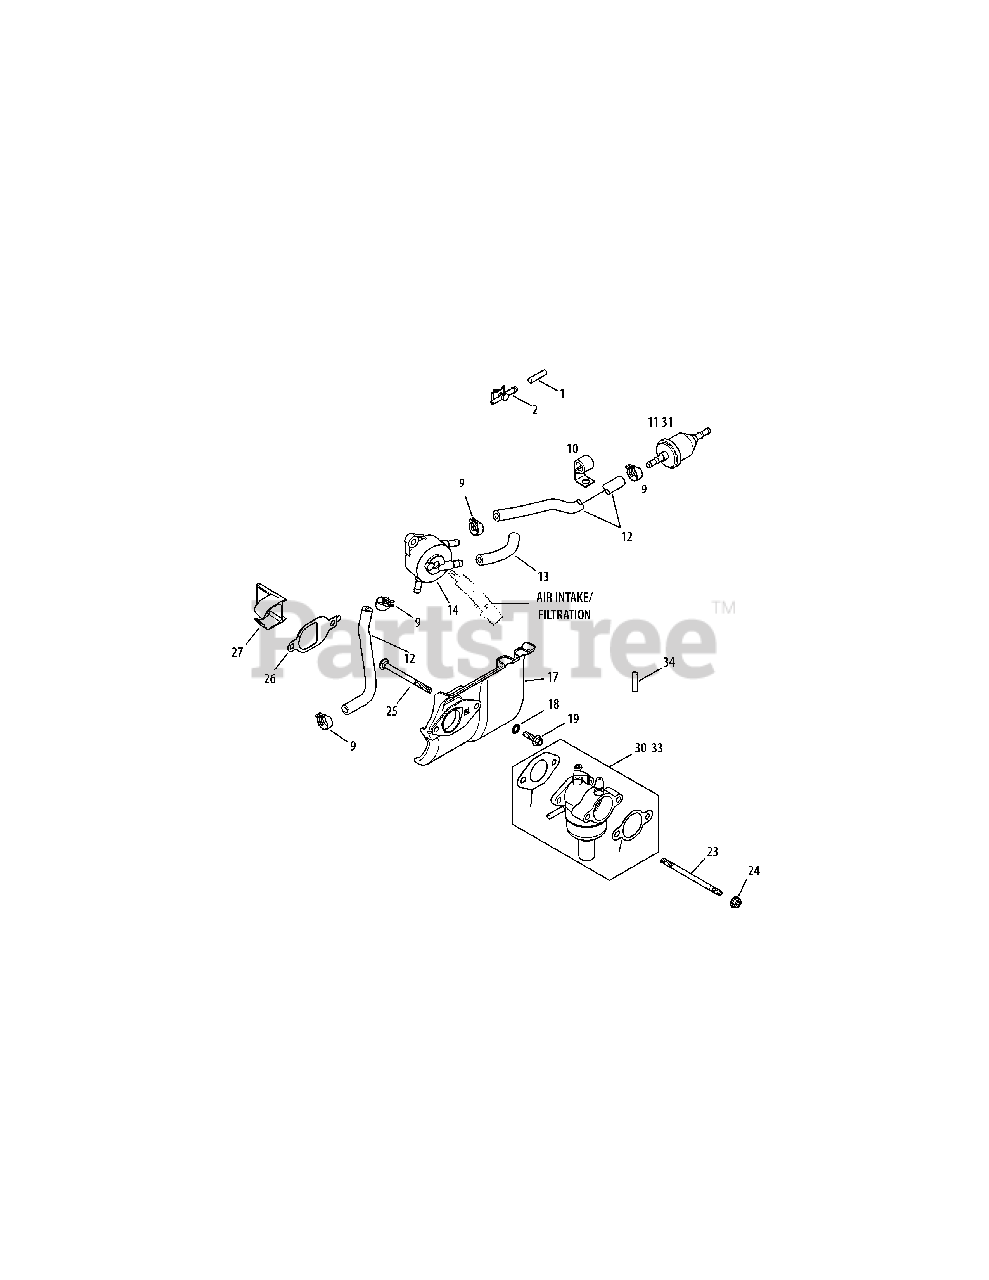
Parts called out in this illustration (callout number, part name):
2	SAI Connector
9	Hose Clamp, 1/2
11	Fuel Filter
12	Fuel Line
17	Heat Deflector Kit
18	Int. Tooth Lock Washer, 1/4
19	Flange Screw, M6 X 1.0 X 20
21	Carburetor Gasket
22	Air Cleaner Gasket
23	Stud, M6 X 1.0 X 100
24	Flange Nut, M6 X 1.0
25	Carburetor Stud
26	Heat Deflector Gasket
27	Intake Port Insert
30	Carburetor (Inc. 21 & 22)
33	Carb Tier III Walbro (Inc. 21 & 22)
